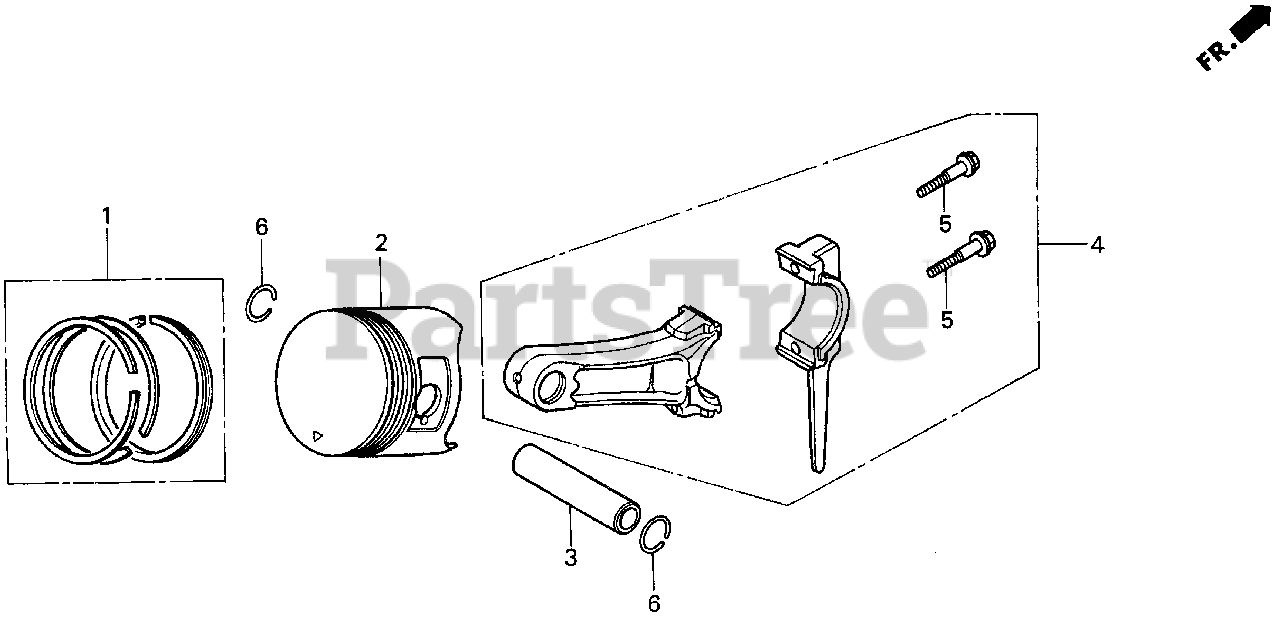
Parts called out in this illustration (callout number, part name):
1	RING SET, PISTON (STD)
1	RING SET, PISTON (OS 0.25)
1	RING SET, PISTON (OS 0.50)
1	RING SET, PISTON (0.75)
2	PISTON (STD)
2	PISTON (OS 0.25)
2	PISTON (OS 0.50)
2	PISTON (0.75)
3	PIN, PISTON
4	ROD ASSY., CONNECTING (STD)
4	ROD ASSY., CONNECTING (US 0.25)
5	BOLT, CONNECTING ROD
6	CLIP, PISTON PIN (20MM)
